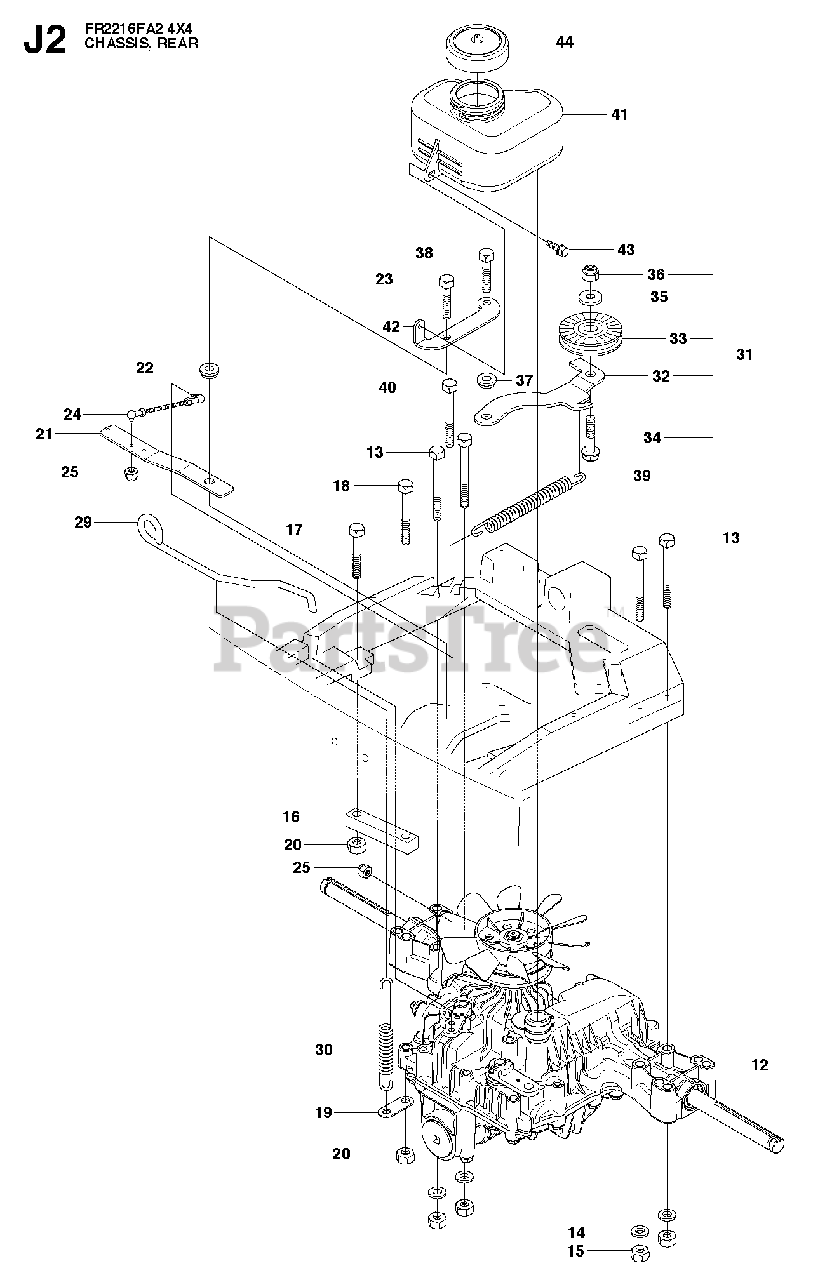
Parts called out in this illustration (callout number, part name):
12	HYDRAULMOTOR
14	WASHER BRB 8.4X17
15	NUT
19	CONNECTOR
20	NUT
22	WASHER
23	SCREW 8X20
25	LOCKNUT M5
30	SPRING
31	TENSIONER
32	TENSIONER
33	PULLEY
34	SCREW
35	SPACER
36	LOCKNUT M8
37	WASHER
38	SCREW 8X20
